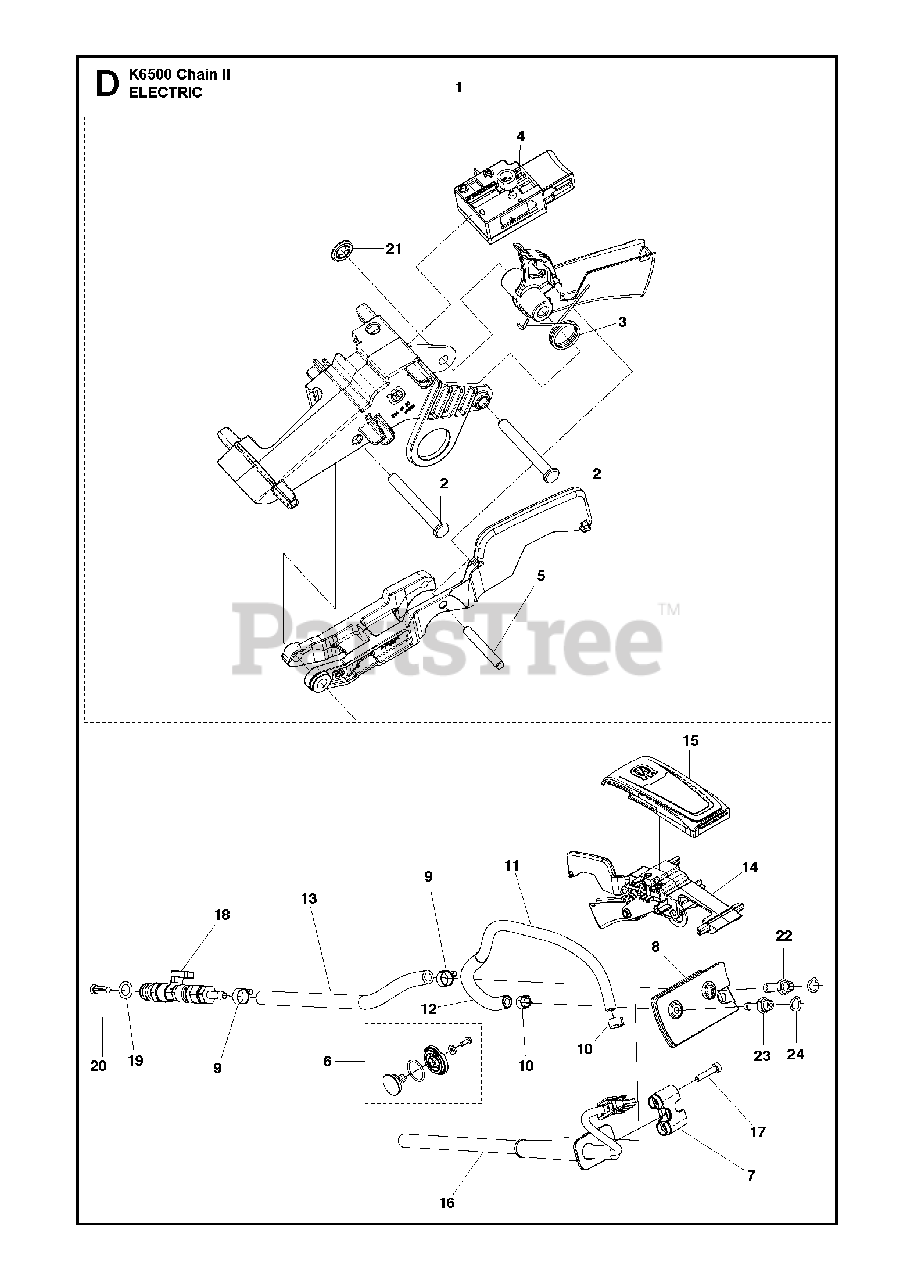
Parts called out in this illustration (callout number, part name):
5	PARALLEL PIN
12	PROTECTIVE SPRING
17	SCREW ITXSCT
